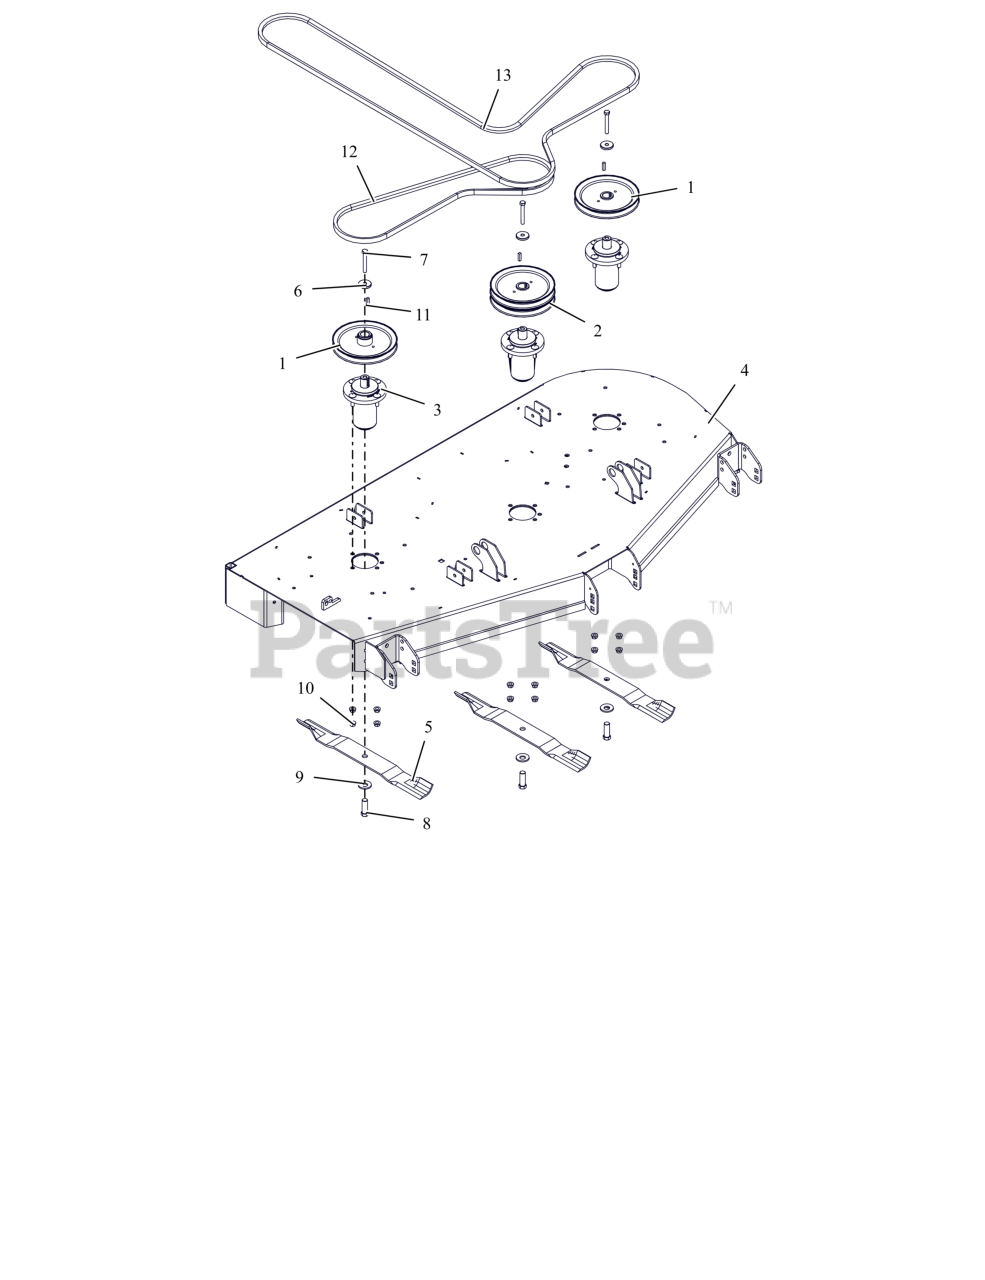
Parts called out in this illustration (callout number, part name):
1	PULLEY, V-7.50 OD X 1"ID
2	PULLEY, DOUBLE 1"X7.50"&7.50" (BLACK)
3	ASM, MAINT FREE ALUM SPINDLE
4	KIT,DECK-60" W/DECALS-ARIENS
5	BLADE, 20.5"
6	RETAINER, SHEAVE
7	BLT, HEX .38-16X2.75 G8 ZCC
8	BLT, HEX .62-18X1.75 G8 ZCC
9	WSHR-BLVL .669X1.535X.138
10	NUT-LK-CTR-FLG .375-16 GF ZCC
11	KEY, SQ .25X.25X1.00 RC 40-50
12	V-BELT, B-COGGED
13	V-BELT, HB SECTION
